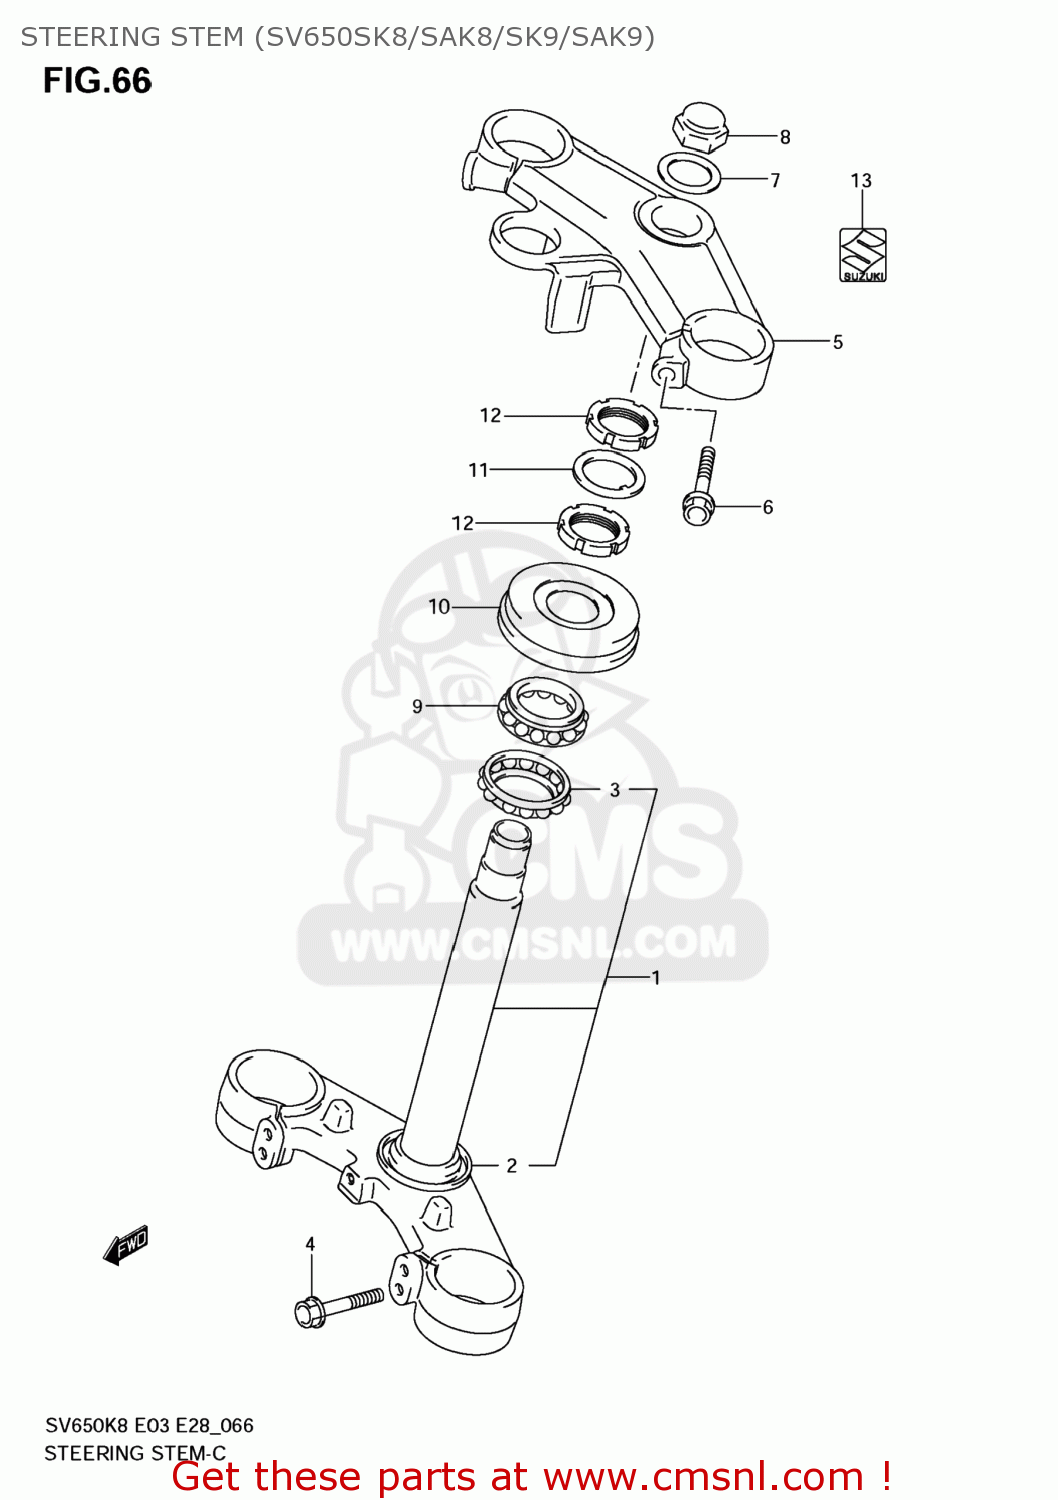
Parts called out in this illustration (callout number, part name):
1	STEM,STEERING
2	SEAL,STEERING LWR
3	BEARING(30X55X17)
4	BOLT(8X40)
5	HEAD,STEERING STEM
6	BOLT(8X40)
7	WASHER
8	NUT
9	BEARING(30X55X17)
10	SEAL,STEERING UPR DUST
11	WASHER,STEERING STEM
12	NUT,STEERING STEM
13	EMBLEM,S
